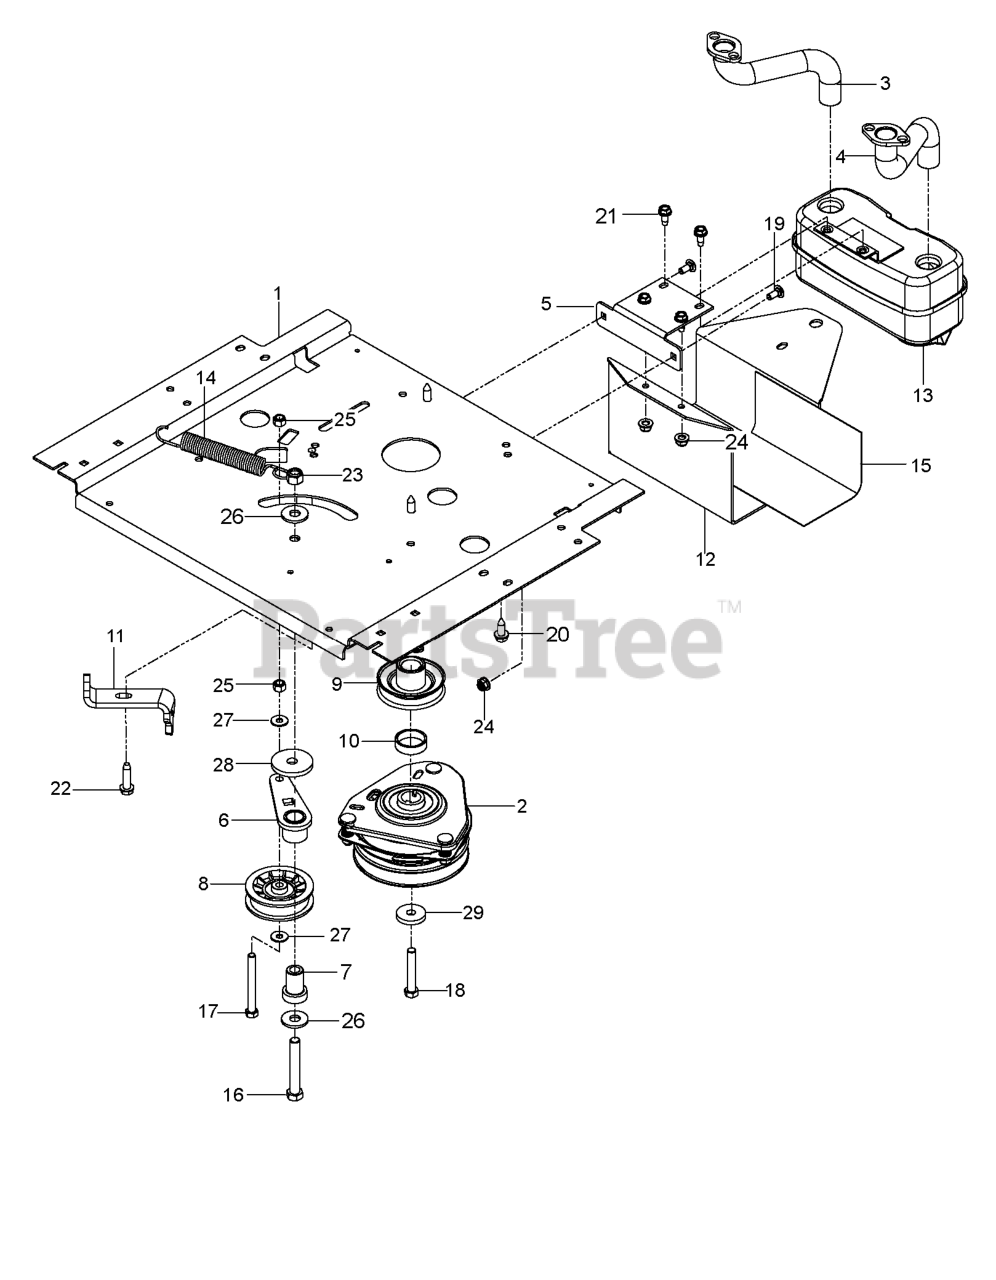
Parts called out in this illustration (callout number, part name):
1	PLATE, ENGINE WIDE, BLACK
2	CLUTCH.ELECTRIC.LT.48"*
3	RP.EXHAUST.TUBE.LH.BS/TWIN
4	EXHAUST.TUBE.RH.BS/TWIN
5	BRACKET, MUFFLER, BLACK
6	RP.IDLER ARM WELDMENT
7	IDLER SPINDLE
8	PULLEY, IDLER RAKE & ZTR
9	PULLEY, ENGINE
10	SPACER, HUB PULLEY
11	STOP, CLUTCH BLK
12	GUARD, MUFFLER, BLACK
13	MUFFLER ASM TWIN
14	SPRING, DECK DRIVE
15	HEAT SHIELD
16	HCS 1/2C X 3 1/4
17	HCS 3/8-16X3-1/2 TAPBLT GR5 ZD
18	HCS 7/16-20 X 2.5 GR8
19	BOLT 5/16C X 3/4" CARRIAGE
20	SCREW 3/8-16X1
21	SCREW.THDROL.5/16-18X3/4.TTY
22	SCREW LT
23	NUT.LK.W/WSH.1/2.
24	5/16-18 NYLOC FLANGE NUT
25	NUT 3/8-16 NYLOC
26	WASHER.9/16 X 1 3/8 X 12 GA.
27	WASHER.5/16.FLAT.STE.STD.
28	HEAVY WASHER
